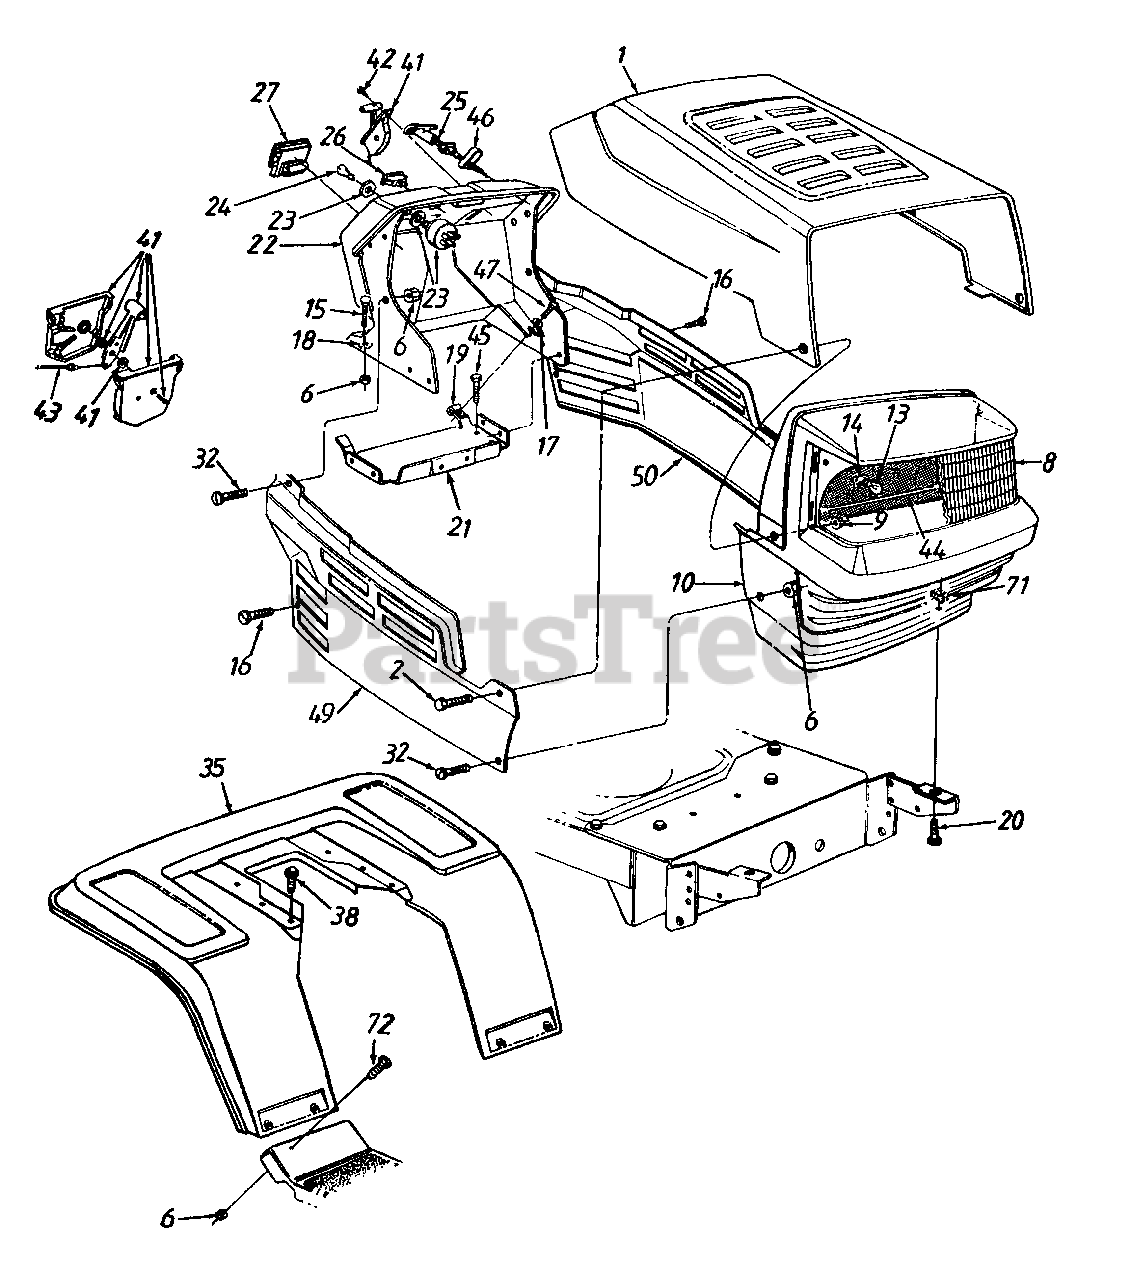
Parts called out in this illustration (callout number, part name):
6	Hex Sems Nut 1/4-20 Thd.
8	Headlight Lens
9	Flange L-Nut 1/4-20 Thd.
10	Grille
13	Lamp
14	Socket
15	Carriage Bolt 1/4-20 x .75" Lg.
16	Hex Wash. Hd. TT-Tap Scr. 1/4-20 x .5" Lg.
17	Fl-Wash. .281" I.D. x .73" O.D.
18	Bolt Retainer 1/4" I.D.
19	Speed Nut 1/4-20 Thd.
20	Hex Bolt 5/16-18 x .75" Lg.
23	Ignition Switch
24	Ignition Key
25	Choke Control
26	Light Switch
27	Ammeter
32	Truss Mach Scr. 1/4-20 x .5" Lg.
41	Throttle Box Ass'y.
42	Truss Mach. AB-Tap Scr. #10 x .5" Lg.
43	Throttle Control Wire
44	Grille Reflector Label
45	Hex Wash. Hd. B-Tap Scr. 5/16-18 x 5" Lg.
46	Choke Retainer
47	Hex TT-Tap Scr 1/4-20 x .75" Lg.
